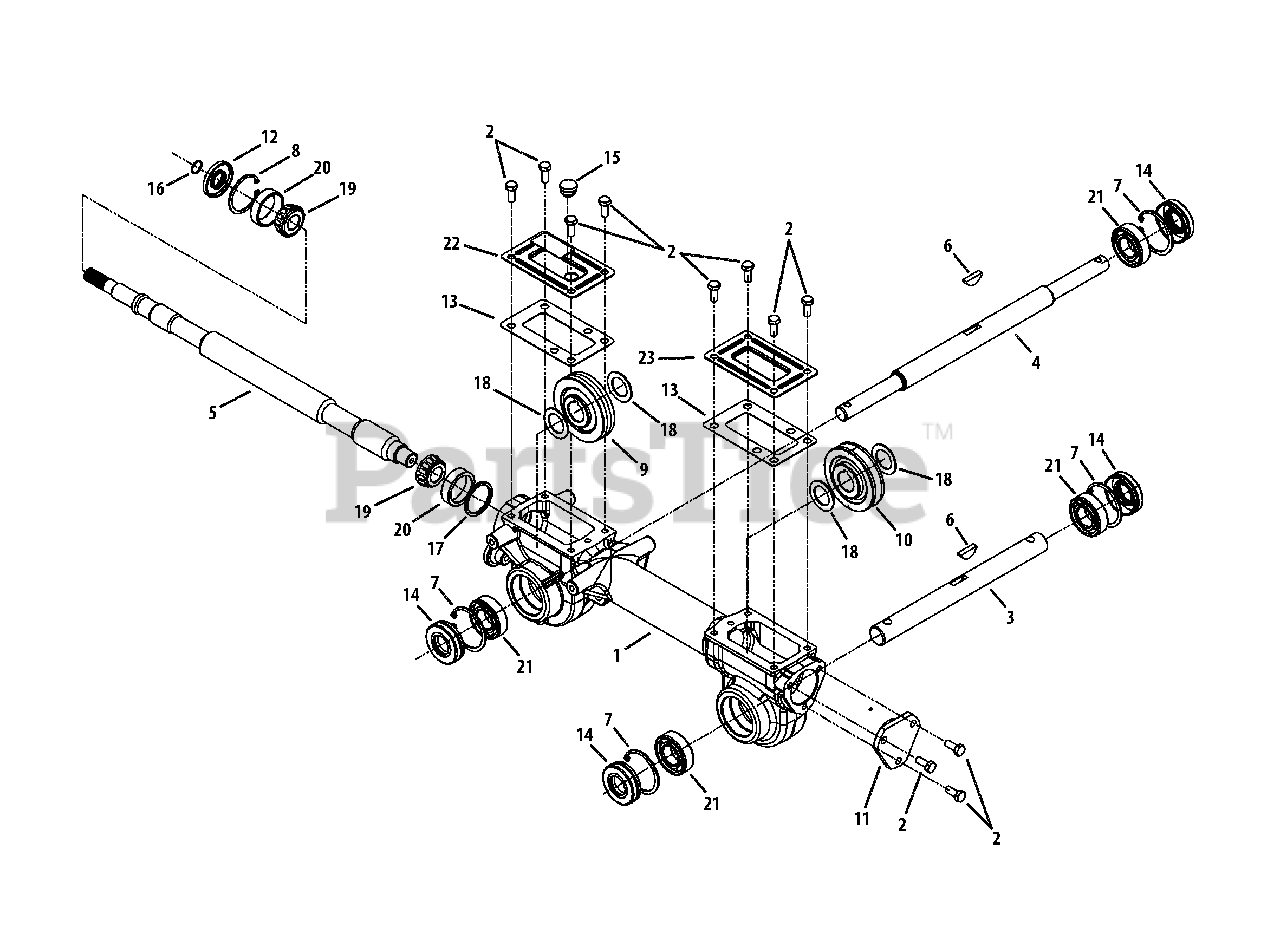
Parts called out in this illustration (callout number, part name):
1	Housing, Transmission
2	Hex Screw, 5/16-18, .75, Gr5
3	Shaft, Tiller
4	Shaft, Wheel
5	Shaft, Worm
6	Key, Hi Pro .25 x 1.062
7	Retaining Ring
8	Retaining Ring, Int
9	Worm Gear, 61t, RH
10	Worm Gear, 30t, LH
11	Bearing Cover
12	Seal, Oil, .750 Shaft x 1.783 Bore
13	Gasket, Gear Housing
14	Seal, Oil, 1.00 Shaft x 2.00 Bore
15	Rubber Plug, Oil
16	Wire Ring
17	Washer, Flat, 1.50 x 1.75 x .062
17	Washer, Flat, 1.50 x 1.75 x .005
17	Washer, Flat, 1.50 x 1.75 x .03
17	Washer, Flat, 1.50 x 1.75 x .010
18	Washer, Flat, 1.010 x 1.56 x .060
19	Cone Bearing
20	Bearing Cup
21	Ball Bearing
22	Cover, Transmission
23	Cover, Transmission
